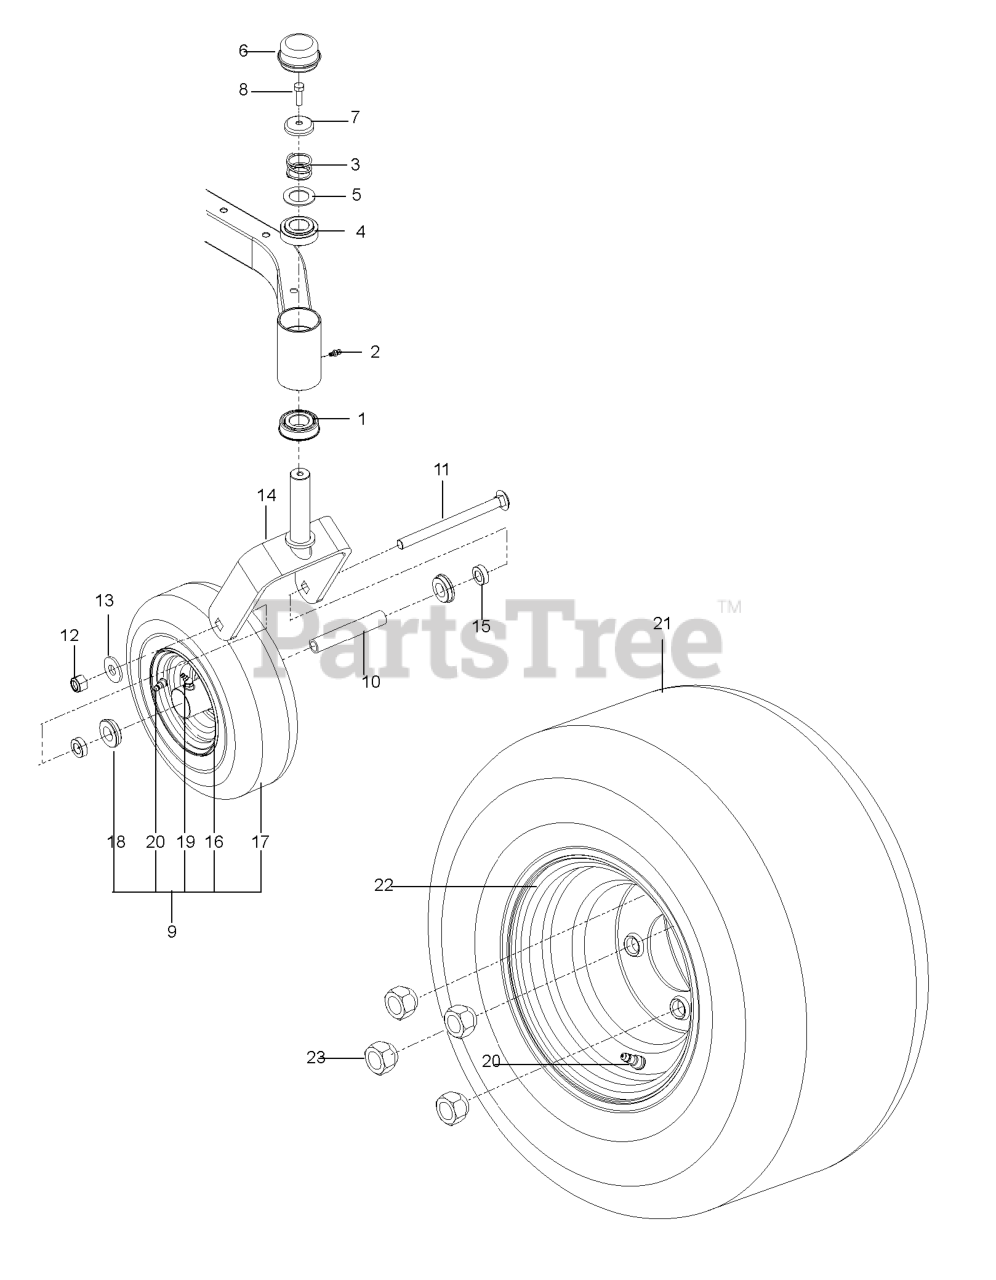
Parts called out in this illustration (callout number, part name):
1	BEARING FLANGED
2	ZERK, 3/16, DRIVE IN
3	SPRING, CASTER
4	BUSHING, CASTER
5	WASHER, 1.025 ID X 1.64
6	GREASE CAP
7	CASTER.PLUG
8	5/16-18X1 HHB G5W/NY
9	TIRE.CASTER.ASSEM.11X4-5.GR
11	RHSNB 1/2-13 X 6.50 GR2 ZD
12	NUT 1/2-13 HEX NYLOC ZD
13	WASH USS FLAT 1/2
14	YOKE.CASTER.ORANGE
15	SPACER, 5/16"
17	TIRE.11"X4"-5.4PLY.SMOOTH.KEND
18	BEARING RETAINER
19	ZERK
20	VALVE STEM TR-412
21	TIRE ASM 18 X 8.5-8
22	RIM.8X7.SILVER.ZTR
23	LUG NUT 1/2F
